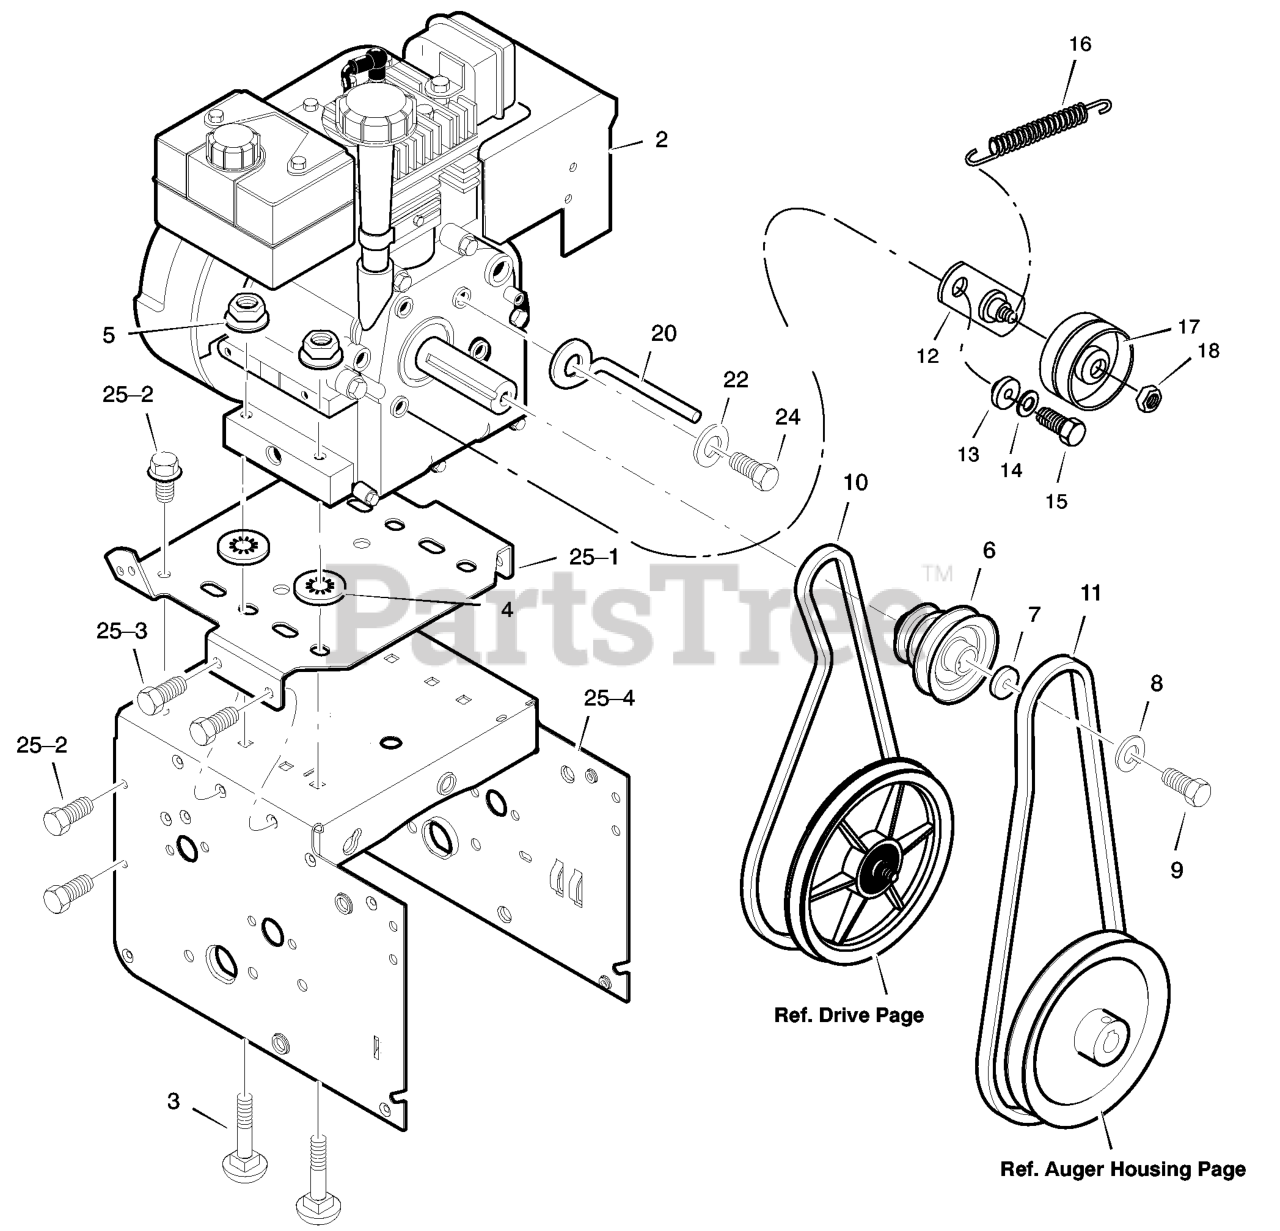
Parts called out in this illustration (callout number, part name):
2	ENGINE
3	BOLT, CARRIAGE 5/16-18
4	RETAINER, PUSH
5	NUT 5/16-18
6	PULLEY, ENGINE
7	WASHER
8	WASHER .38ID
9	SCREW, 3/8-24 x 1.00
10	BELT, V 3L
11	BELT, V 4L
12	BRACKET ASSEMBLY, IDLER
13	BUSHING, IDLER BRACKET
14	WASHER, SPLIT
15	SCREW 5/16-24 X 0.75
16	SPRING, IDLER TRACTION DRIVE
17	PULLEY, IDLER
18	NUT, JAM 3/8-16
20	GUIDE, BELT
22	WASHER .31X.58X.08
24	SCREW, 5/16-24 x 0.75
25-1	PLATE, ENGINE MOUNT
25-2	SCREW, TAP 1/4-20 X .63
25-3	SCREW, TAP 5/16-18 X .50
25-4	FRAME, MOTOR BOX
